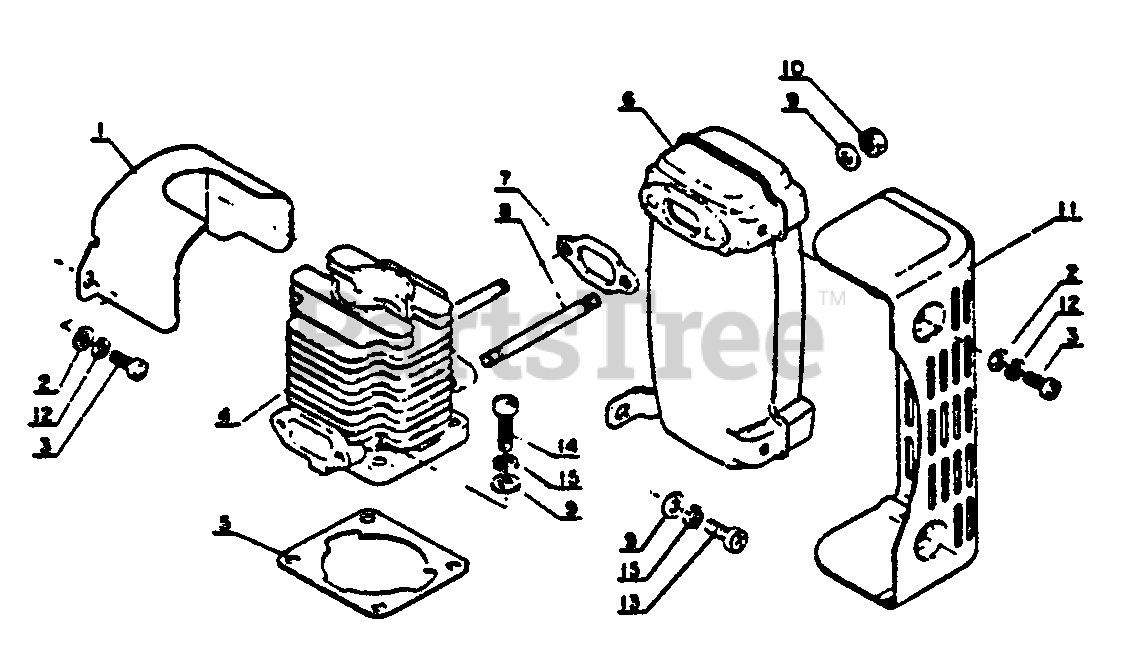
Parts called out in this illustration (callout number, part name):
1	SHIELD, CYLINDER
2	WASHER 4 MM
3	SCREW 4×10
4	CYLINDER
5	GASKET, CYLINDER
6	MUFFLER
7	GASKET, MUFFLER
8	STUD
9	WASHER, FLAT 5.5×10×0.8
10	LOCKNUT - 5
11	COVER, MUFFLER
12	WASHER, SPRING 4 MM
13	SCREW - 5×10
14	SCREW 5×18
15	WASHER, SPRING 5
